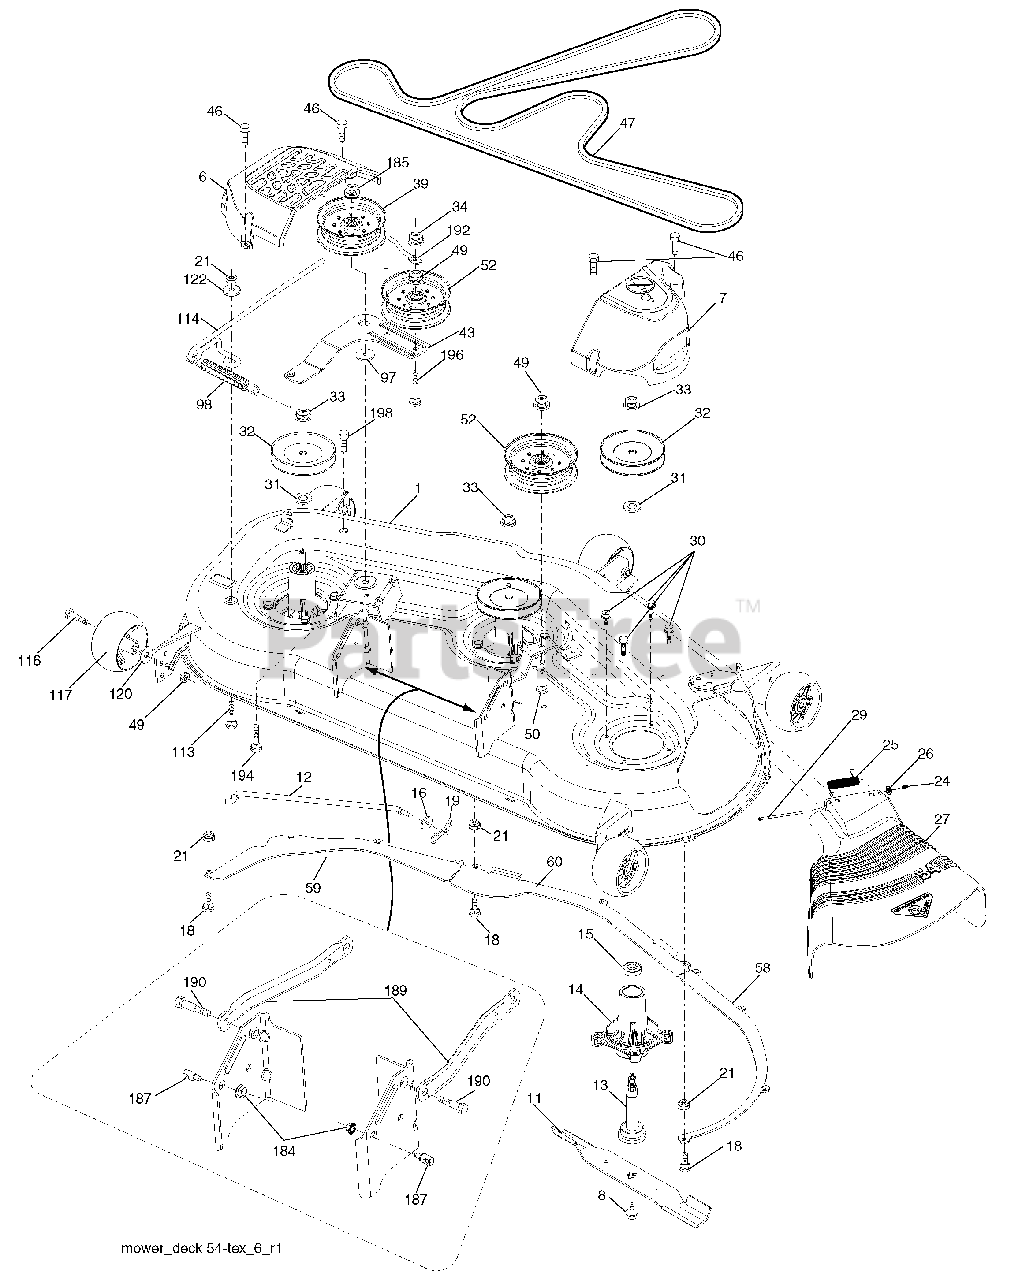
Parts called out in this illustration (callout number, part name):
1	Deck Weldment Mower
6	Cover Mandrel LH
7	Cover Mandrel RH
8	Bolt 7/16 Asm. Blade
11	Blade Discharge/Bagging
12	Rod-Anti Sway
13	Shaft Asm. w/Lower Bearing
14	Housing, Mandrel
15	Bearing, Ball, Mandrel
16	Washer 13/32 x 13/16 x 12 Ga.
18	Bolt 5/16 - 18 x 5/8
19	Pin Cotter 5/16 Bow Tie Lock
21	Nut, Crownlock 5/16-18 unc
24	Cap Sleeve
25	Spring, Torsion
26	Nut, Push
27	Deflector Shield
29	Rod, Hinge
30	Screw, Thdrol. Washer Head
31	Washer, Spacer Mower Vented
32	Pulley, Mandrel
33	Nut, Flg. Top Lock
34	Nut Crownlock 3/8-16 unc
39	Pulley, Idler 4.50 HUB
43	Arm, Idler
46	Screw, Thdrol. 1/4-20 x 5/8
47	V-Belt, Mower
49	Nut, Lock Flg. 3/8-16 unc
50	Bolt Rdhd. Sqnk. 3/8-16 unc x 2
52	Pulley Idler
58	Baffle Right
59	Baffle Left
60	Baffle Center
97	Washer Hardened
98	Spring Drive
113	Bolt Rdhd. Sqnk. 5/16-18 x 3/4
114	Rod Tension Relief
116	Bolt, Shoulder
117	Gauge Wheel
120	Washer 13/32 x 1-1/4 x 12 Ga.
122	Bushing Tension Relief
184	Nut Lock Hex Flange 5/16-18
185	Nut Lock Flange 7/16-14 Gr. 5
187	Stud Fastener w/"D" Anti-Rotation
189	Arm Susp. Mower Rear
190	Bolt Shoulder
192	Keeper Belt Idler
194	Bolt Carr. Sqnk. 3/8-16 x 2-1/4
196	Bolt Rdhd. Sqnk. 3/8-16 x 2-1/2 Gr. 5
198	Screw Thdrol. 3/8-16 x 1/2
198	Mandrel Asm. Service
198	Replacement Mower, Complete
